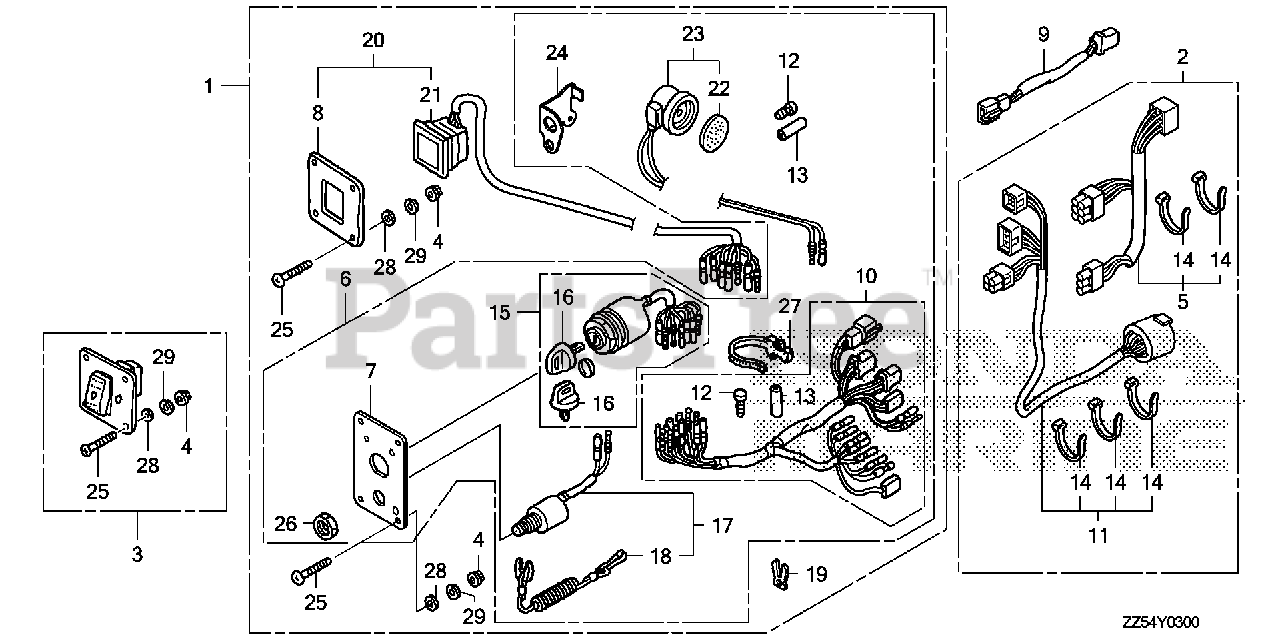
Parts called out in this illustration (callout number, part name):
1	PANEL KIT, SWITCH (4-LED) (B)
2	CABLE SET, PANEL INDICATOR (20FT)
2	CABLE SET, PANEL INDICATOR (25FT)
2	CABLE SET, PANEL INDICATOR (30FT)
3	SWITCH KIT, LIGHT
4	NUT, FLANGE (5MM)
5	WIRE ASSY., INDICATOR (20FT)
5	WIRE ASSY., INDICATOR (25FT)
5	WIRE ASSY., INDICATOR (30FT)
6	PANEL ASSY., SWITCH
7	PANEL, CONTROL
8	PANEL, CONTROL
9	SUB-HARNESS ASSY., POWER TRIM-TILT (A)
10	HARNESS ASSY., SWITCH PANEL
11	CABLE ASSY., SWITCH PANEL (25FT) (NHK MEC)
11	CABLE ASSY., SWITCH PANEL (20FT)
11	CABLE ASSY., SWITCH PANEL (30FT)
12	PLUG, CONNECTOR (INNER)
13	PLUG, CONNECTOR (OUTER)
14	TIE, CABLE (2.4X92) (NATURAL)
15	SWITCH ASSY., COMBINATION
16	KEY ASSY., COMBINATION SWITCH (35100-ZV5-003 ONLY)
17	SWITCH ASSY., EMERGENCY STOP
18	WIRE, EMERGENCY
19	CLIP, EMERGENCY LOCK
20	PANEL ASSY., INDICATOR (4-LED)
21	LAMP ASSY., INDICATION (4-LED)
22	PLATE, TURN SIGNAL BUZZER
23	BUZZER, WARNING
24	BRACKET, BUZZER
25	SCREW, PAN (5X40)
26	NUT, HEX. (16MM)
27	BAND, WIRE HARNESS (150MM) (NATURAL)
28	WASHER, PLAIN (5MM)
29	WASHER, SPRING (5MM)
